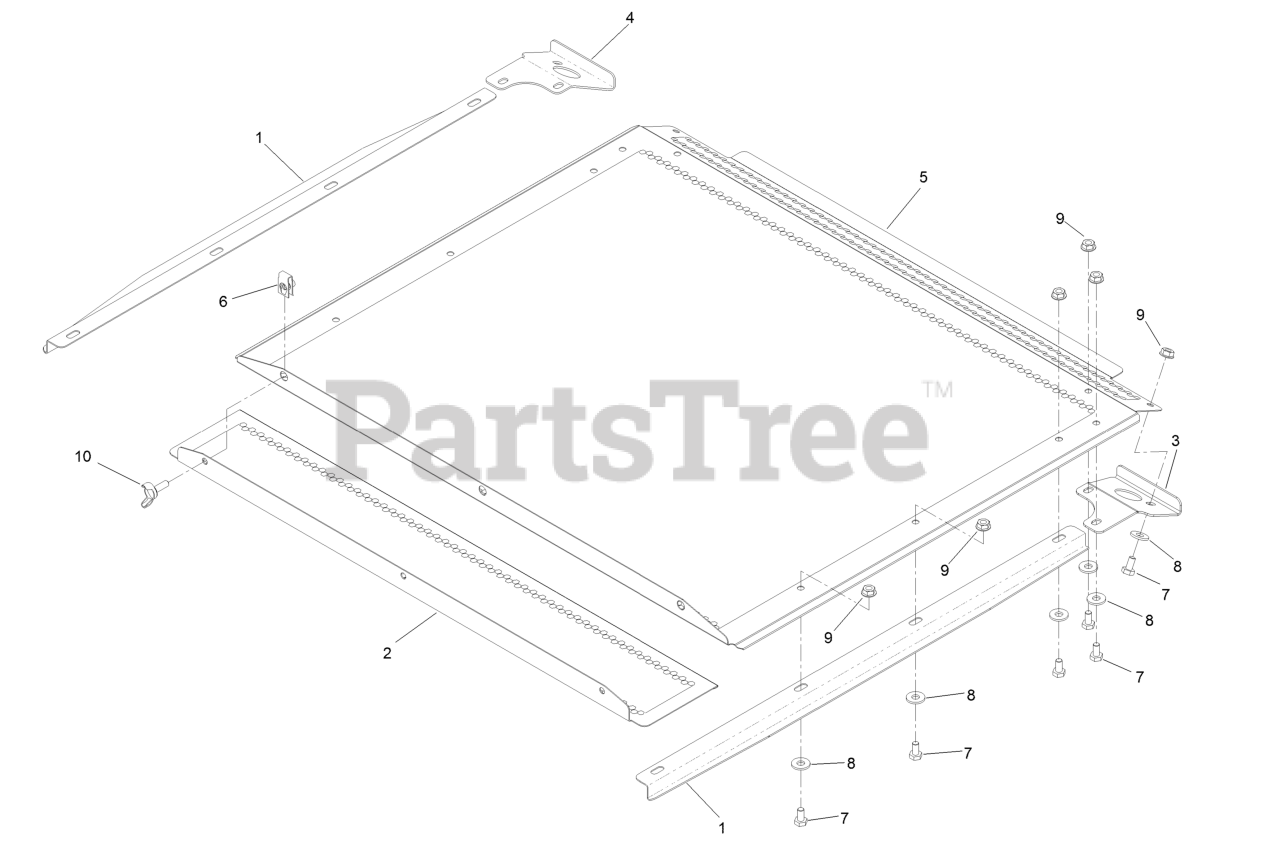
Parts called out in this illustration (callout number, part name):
1	Guide-Screen
2	Panel-Screen, Removable
3	Handle-Screen, LH
4	Handle-Screen, RH
5	Panel-Screen, Hopper
7	Screw-HH
8	Washer-Flat
10	Screw-Wing
